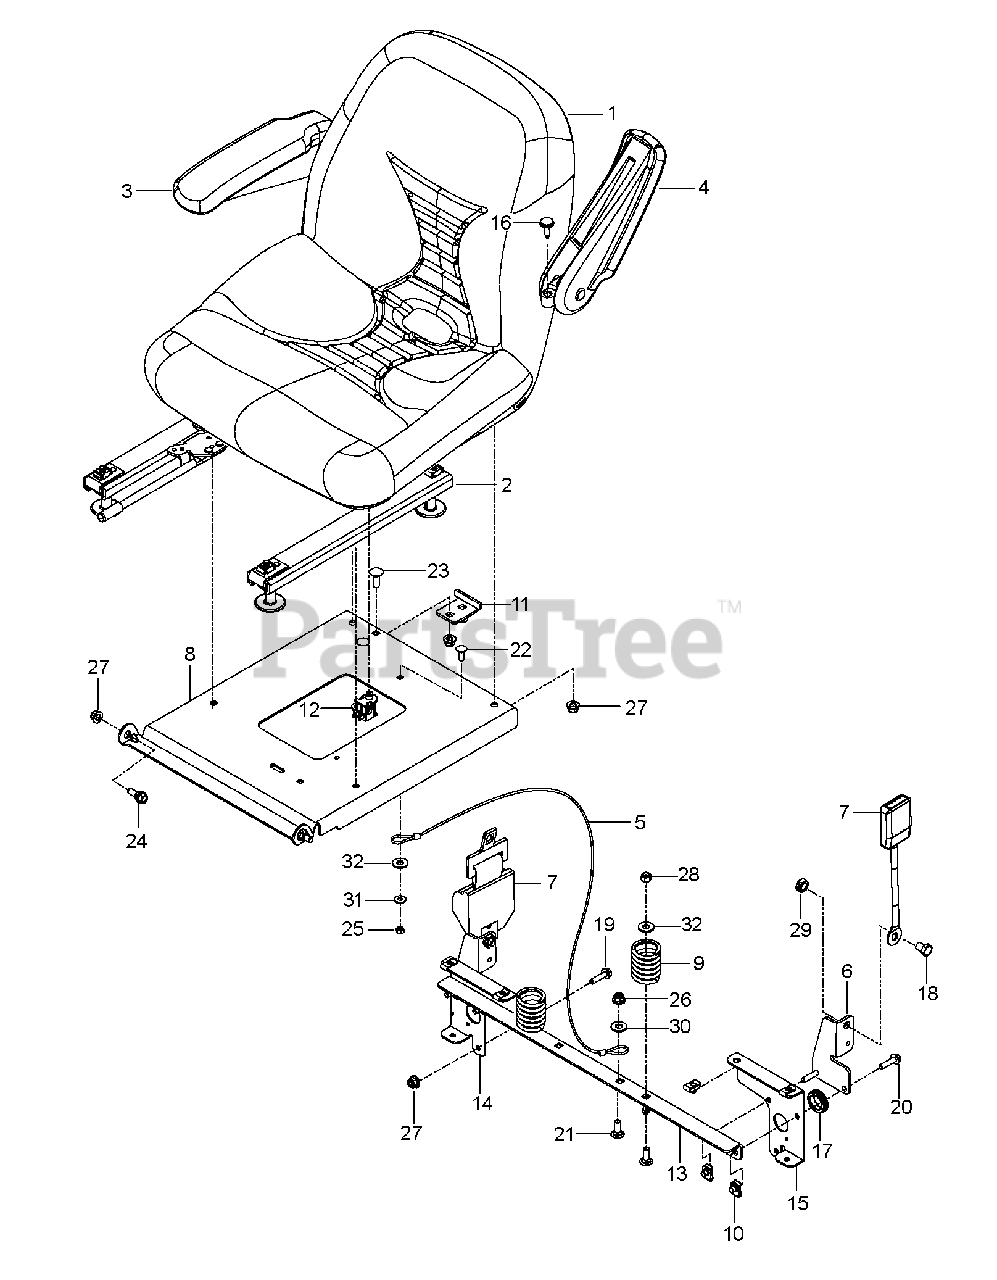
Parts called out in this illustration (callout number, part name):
1	SEAT
2	TRACK ADJUSTMENT KIT
3	ARMREST KIT, RT SQUARE END
4	ARMREST KIT, LT SQUARE END
5	SEAT LANYARD
6	MOUNT.SEAT.BELT.BLACK
7	Seat Belt, Retractable
8	SUPPORT.SEAT.ORANGE
9	SPRING.COMPRESSION.SEAT.BLACK
10	U-CLIP 5/16-18 NUT RETAINER
11	STOP, SEAT - BLACK
12	SWITCH.SNAPMOUNT.NC
13	SUPPORT.SEAT. BLK
14	SUPPORT.RT.BLK
15	SUPPORT.LT.BLK
16	ADJUSTER KNOB
17	RUBBER GROMMET
18	HCS 7/16-20 X .75 GD 5
19	HHFS 5/16-18 X 3/4
20	HHFS 5/16-18 X 1.25 TPBLT GD 5
21	BOLT D
22	BOLT
23	RHSNB 5/16-18 X 3/4
24	SB 5/16-18 HEX HD GD5, BLK ZN
25	LOCKNUT.NYLOC.1/4-20
26	NUT 3/8-16 HEX FLG NYLOC ZD
27	5/16-18 NYLOC FLANGE NUT
28	NUT
29	NUT HEX 7/16F LOCK RP
30	NUT 5/16 NYLOC
32	WASHER 3/8 FLAT
